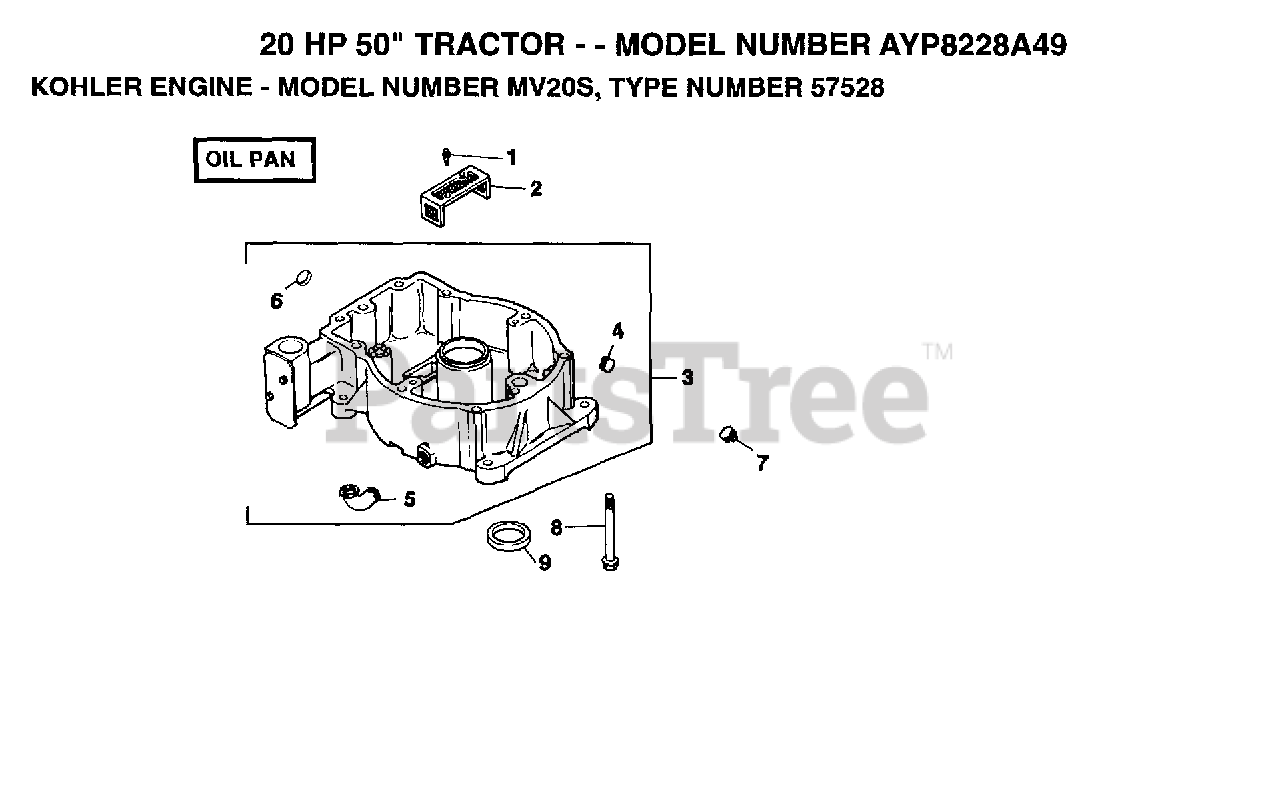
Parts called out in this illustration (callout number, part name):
1	SCREW
4	PLUG, CUP 1-1/16
5	ELBOW, STREET
6	PLUG, 1/4
7	PLUG
